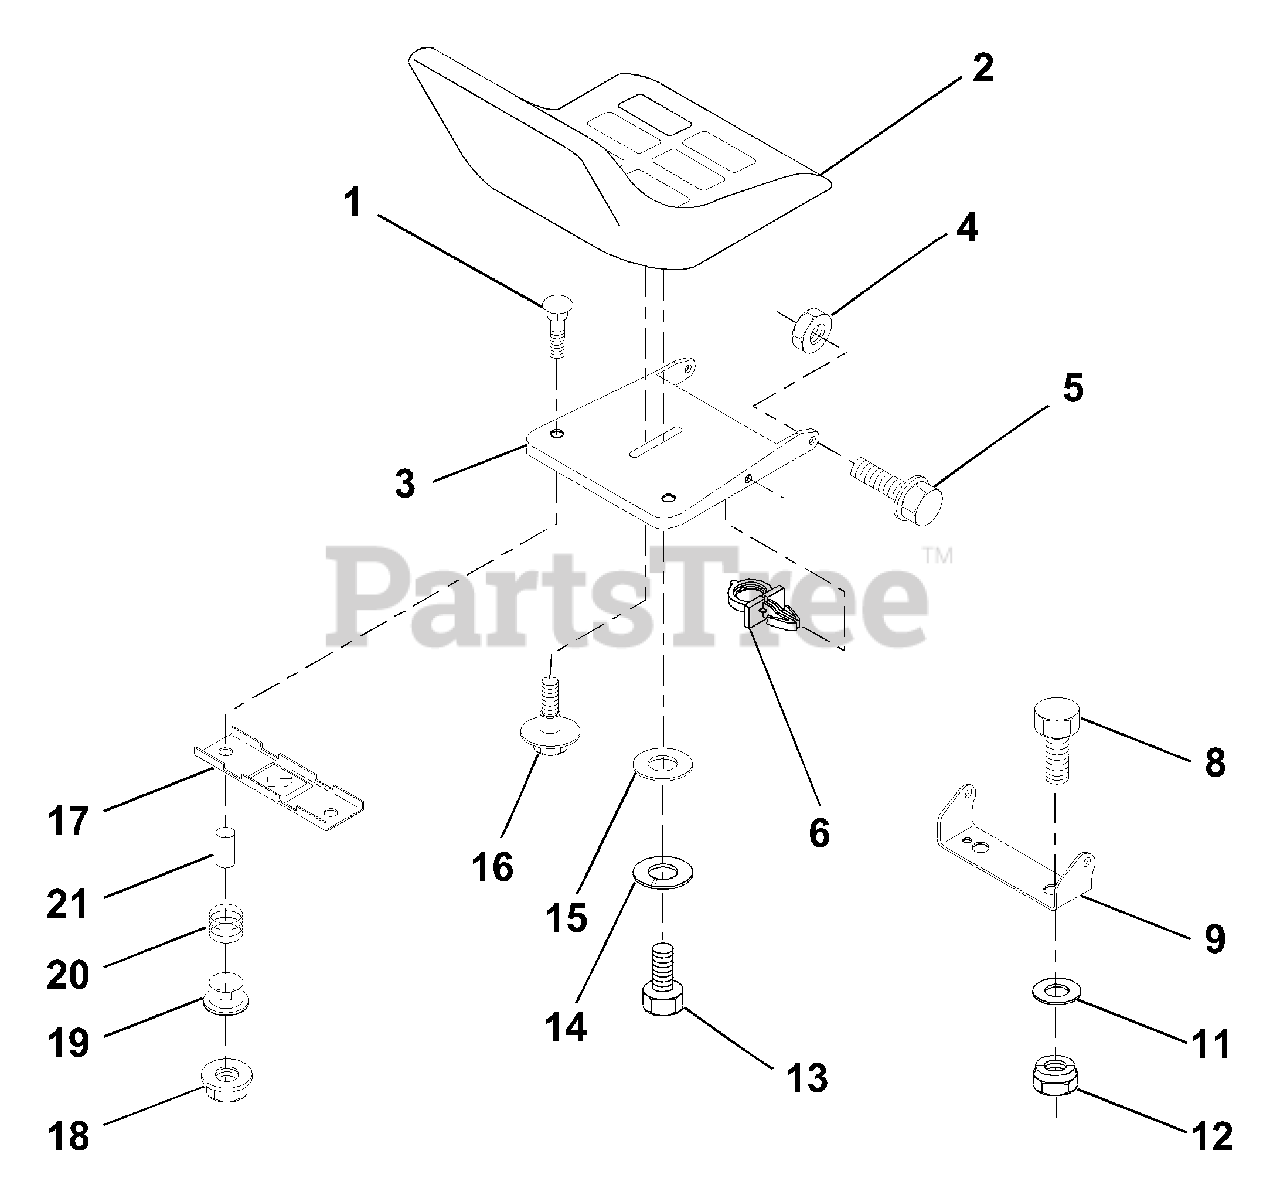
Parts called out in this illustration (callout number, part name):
1	Bolt, Carriage 1/4-20 x 1-1/2
2	Seat
3	Pan, Seat
4	Locknut, Hex w/Ins 5/16-18
5	Bolt, Shoulder 5/16-18 UNC
6	Clip, Push-in
8	Bolt, Fin Hex 3/8-16 UNC x 1
9	Bracket, Pivot Seat
11	Washer 12/32 x 2 x 10 Ga.
12	Nut, Lock Hex w/Wsh 3/8-16
13	Bolt Hex 1/2-13 x 7/8
14	Washer Lock Hvy. Hlicl Spring 1/2
15	Washer, 17/32 x 1-3/16 x 12 Ga.
16	Bolt, Shoulder
17	Bracket, Switch, Mounting
18	Nut, Hex Large Flange Lock
19	Bushing, Snap
20	Spring, Compression
21	Spacer, Split 28 Id. x .88 Lg.
